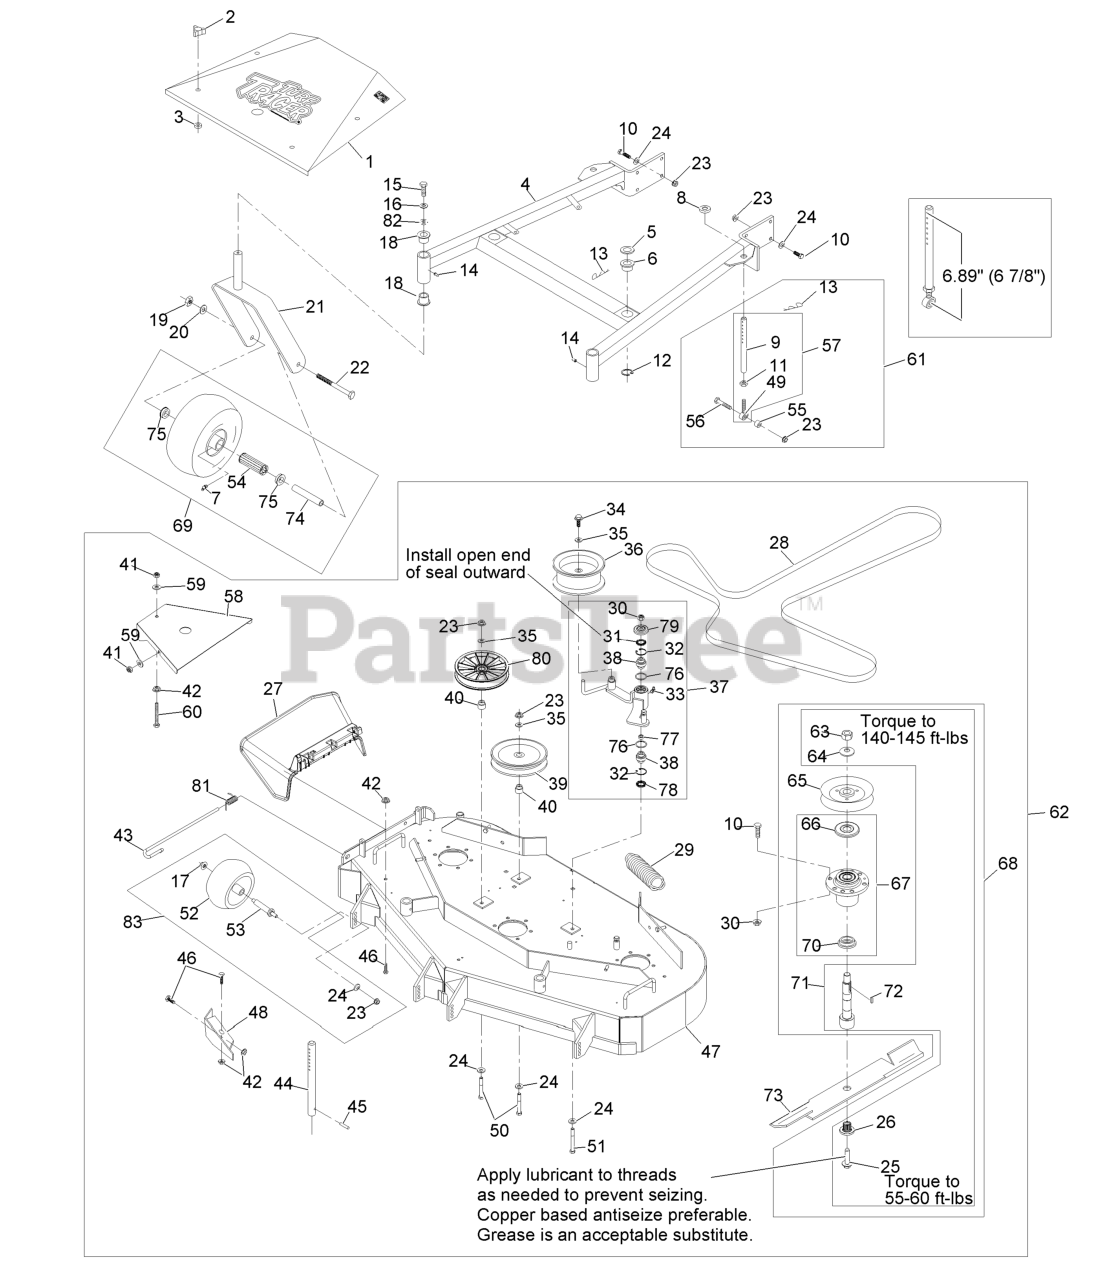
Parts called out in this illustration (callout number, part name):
1	ASM,SHIELD W/DECALS 48 TT
2	KNOB-3 PRONG
4	DECK SUPPORT W/BSHGS 48"
5	SPACER-DECK SUPPORT
6	BUSHING-DECK
7	FITTING-GREASE
9	LINK,SUPPORT
10	SCREW-HH
11	NUT-HJ
12	RING-RETAINING
13	PIN,HAIR COTTER
14	FITTING-GREASE
15	SCREW-HH
16	WASHER-LOCK
17	Nut-Nyloc 3/8-16 Flg
18	BEARING-FLANGED
19	NUT-HH
20	WASHER-LOCK
22	SCREW-HH
23	NUT-HHF, WHIZ
24	WASHER-BELLEVILLE
25	SCREW,SEMS 1/2-20 X 2.19
26	BUSHING,SPLINED
27	CHUTE DEFLECTOR XRK M056
28	BELT - V, B
30	NUT-LOCK, NI
31	SEAL-LIP, SINGLE
32	RING-SNAP
33	FITTING-GREASE, 90 DEG
34	SCREW-HHF
35	WASHER-FLAT
37	KIT, DECK IDLER TTHP48&52
38	BEARING-SPHERICAL
39	PULLEY-IDLER
40	BUSHING-IDLER
41	NUT-LOCK, NI
43	PIN-CHUTE
44	ROD,DECK SUPPORT
46	SCREW-HH
47	ASM,DECK W/DECALS TTHP/MH
48	BAFFLE,DOGLEG
49	BALLJOINT
50	SCREW-HH
51	SCREW-HH
52	ROLLER-SCALP, ANTI
54	BEARING
56	SCREW-HH
58	SHIELD,BELT
59	WASHER-FLAT
60	BOLT,TAP HH
61	KIT,SUPPORT LINK W/PIN
62	Asm, Deck Complete
65	SHEAVE,W/HUB 5.72
66	GUARD-BEARING, TOP
67	KIT, CUTTER HOUSING
68	ASM, CUTTER HSG
69	KIT, SP CASTER WHEEL REPL
70	SPACER-GUARD, BOTTOM
71	KIT, SPLINED SPINDLE 103-
72	KEY-RECTANGLE
75	BUSHING
78	SEAL-LIP, DOUBLE
79	GUARD-TOP
80	PULLEY,IDLER 5"
81	SPRING, TORSION
